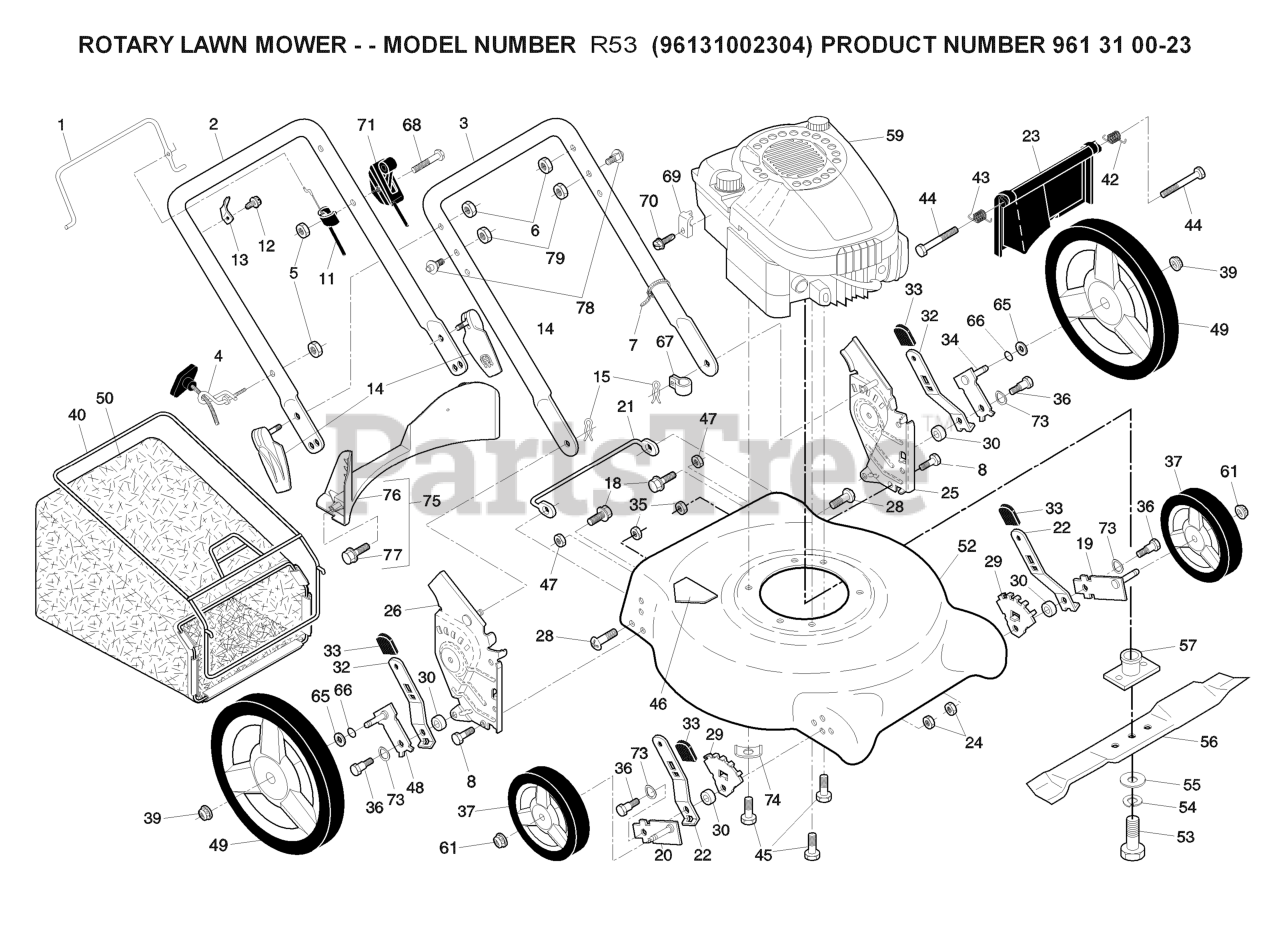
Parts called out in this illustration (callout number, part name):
1	BAIL.MZR.STD.ORANGE
3	HANDLE.LOWER.ECON.PNT
4	RB GUIDE.ROPE.STD.BLK.ZIN WSL
5	NUT
6	NUT.HEX.FLANGE.1/4
7	TIE GUIDE
8	BOLT.FIN.HEX.5/16-18X3/4
11	CABLE.MZR.B&S.45.LT.PUSH
13	BRACKET
14	ASM.QUICK.RELEASE
15	HAIRPIN COTTER
18	SCREW 1/4X20
19	AXLE ARM ASSY FRONT LH
20	AXLE ARM ASSY FRONT RH
22	SELECTOR SPRING, FRONT
23	REAR DOOR ASSY
24	LOCKNUT 5/16-18
25	RP BRKT.ASM.HAND.HW.21.LT.ORNG
26	RP BRKT.ASM.HAND.HW.21RT.ORNG
29	WHEEL ADJ BRACKET FRONT
30	SPACER.HEIGHT.ADJUSTER
32	SPRING.SEL.EXT.21.DOMED.12/14
34	AXLE ARM ASSY REAR LH
35	LOCKNUT 5/16-18
36	SHOULDER BOLT 5/16-18
37	WHEEL AND TIRE ASSY, REAR
39	NUT.HEX.FLANGE.3/8-16.LOCKNUT
40	FRAME.BAG.21.REAR.DOMED.PUSH
42	SPRING.LH.22.REAR.DOOR.EZ.EMPT
43	SPRING.RH.22.REAR.DOOR.EZ.
45	BOLT 3/8-16X1-1/8
46	DECAL.INTERNATIONL.CUTFINGER
48	AXLE ARM ASSY REAR RH
49	RP.WHEEL.12X1.75H 3 SPOKE.RAD
52	KIT.HSG.21.PUSH.ORANGE.CE
53	SCREW, HEX HD 3/8-24 X 1-3/8
54	LOCKWASHER
55	WASHER,HARDEN
56	BLADE.21.PUSH
57	ADAPTER.BLADE.W/KEY.25MM.CE
61	NUT.HEX.FLANGE.3/8-16.LO(3 2)
65	WASHER.FLAT.1/2
66	O-RING..070X.487.NEOPRENE
67	CLIP.CABLE.BLK
69	CABLE CLAMP(ENGINE)
70	SCREW.HEX.HEAD.WASHER.10-16
72	NUT
73	WASHER.CURVED.CYLINDRICAL
74	WASHER.ENGINE.BZP
75	KIT.BAFFLE.REAR.PLASTIC.21.RD
76	BAFFLE.REAR.PLASTIC.21.RD.ECON
77	SCREW.HX.13X.750
78	STUD.QUICK.ADJUST
79	NUT.LOCK.5/16-18
